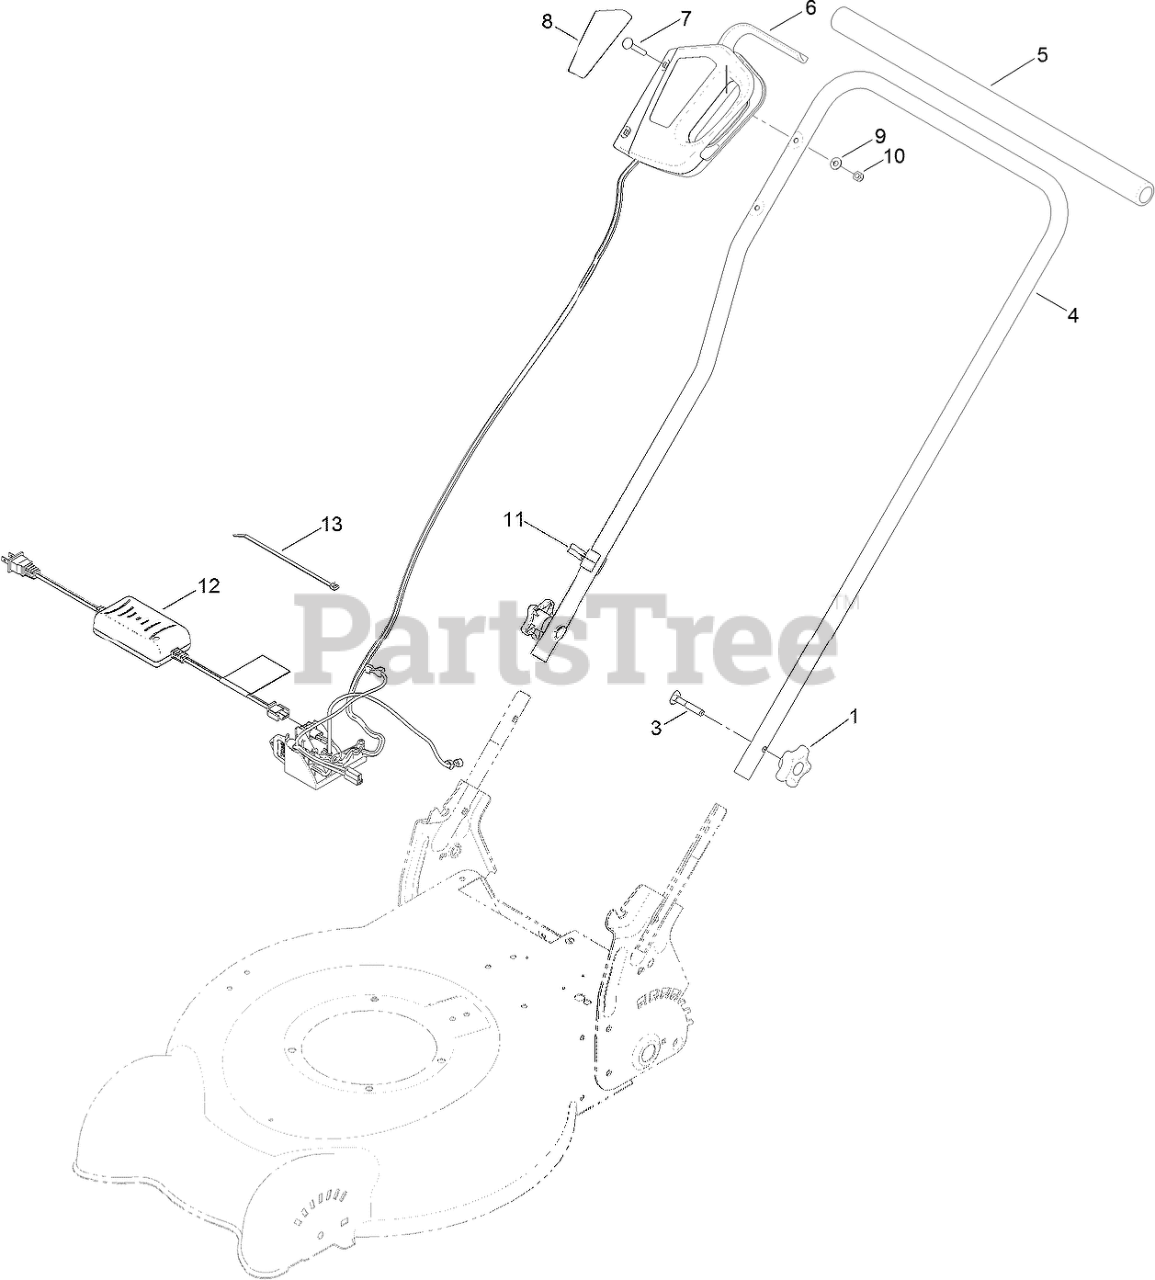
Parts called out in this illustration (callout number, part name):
1	KNOB-HANDLE
3	SCREW-HANDLE
5	FOAM-HANDLE
6	36 VOLT SWITCH ASM
7	SCREW-CARR
8	DECAL-HOUSING, SWITCH
9	WASHER-FLAT
10	NUT-LOCK, NI
11	GUIDE-CABLE
12	CHARGER-BATTERY, CORDLESS WPM
13	TIE-CABLE
